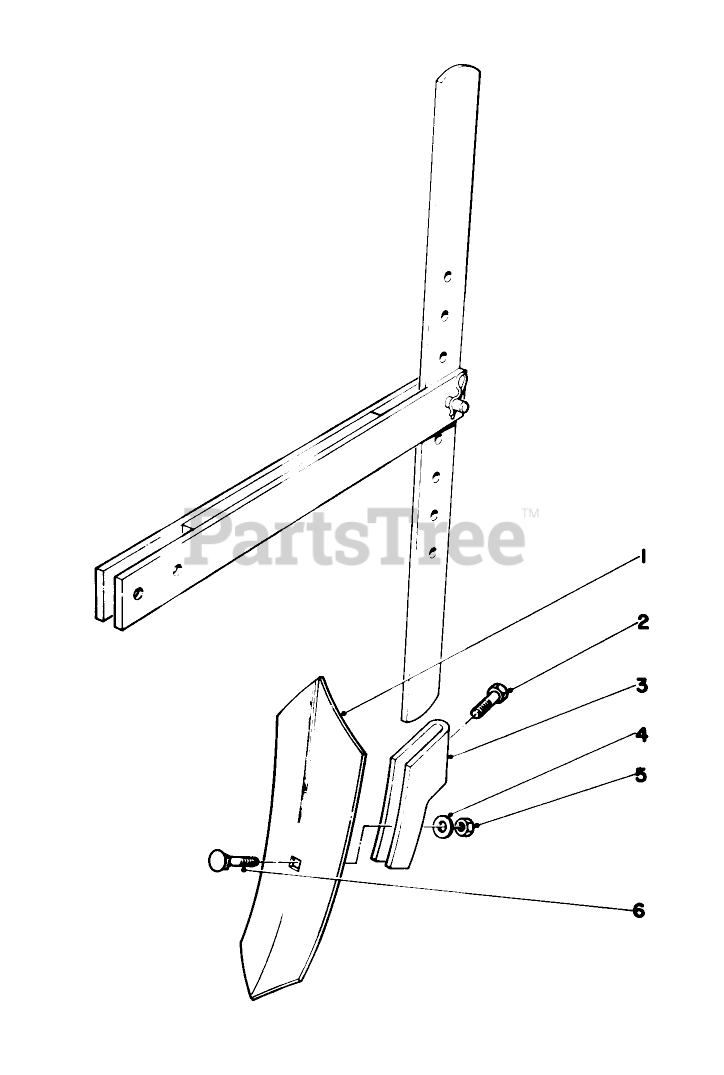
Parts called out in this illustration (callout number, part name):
1	Shovel
2	SCREW-HH
3	Shovel Clamp
4	WASHER-FLAT
5	NUT-HEX
6	SCREW-CARR
